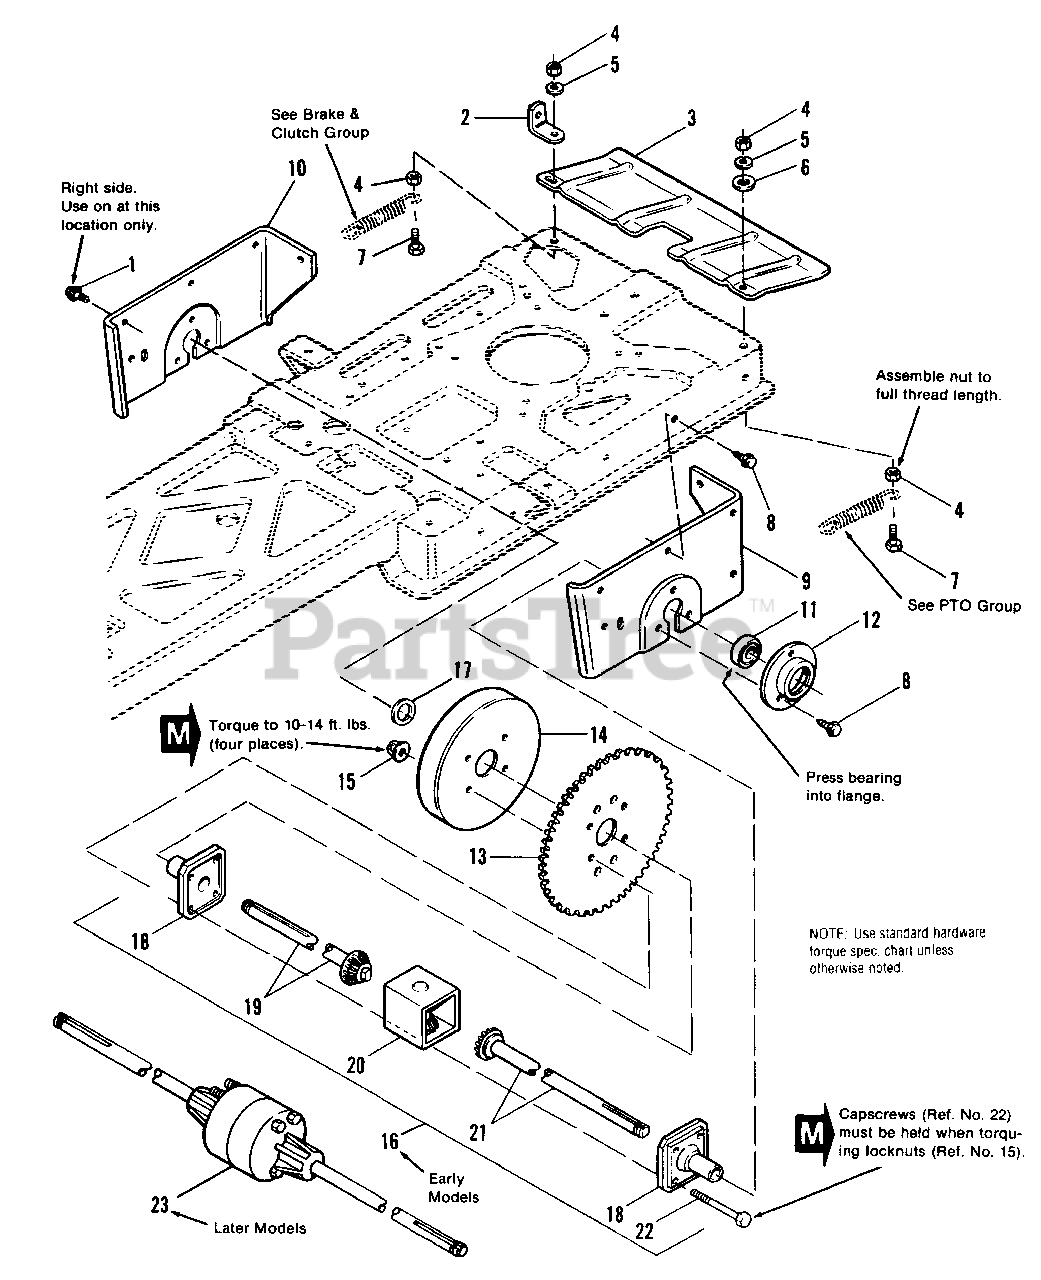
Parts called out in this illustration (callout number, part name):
1	SCREW, Hex, Wash. Hd., Taptite, 5/16-18 x 3/8
3	DEFLECTOR, Heat
4	NUT, Hex, 5/16-18
5	LOCKWASHER, 5/16
6	WASHER, Plain, 5/16
7	CAPSCREW, Hex, 5/16-18 x 1-1/2
8	SCREW, Taptite, Washer Hd., 5/16-18 x 1/2
9	AXLE SUPPORT, L.H.
10	AXLE SUPPORT, R.H.
11	BEARING, Ball
12	FLANGE, Bearing
14	DRUM, Brake
15	LOCKNUT, Hex, Flange, 5/16-18
16	**DIFFERENTIAL SERVICE KIT (Includes Ref. Nos. 13, 14, 15, 17 & 23)
17	WASHER, Plain
18	*END CAP & BEARING ASSY.*
19	*AXLE GEAR ASSY., R.H.*
20	*TRANSMISSION GEAR CASE ASSY.*
21	*AXLE GEAR ASSY., L.H.*
22	*CAPSCREW, Hex, 5/16-18 x 3-1/2*
23	***DIFFERENTIAL AXLE ASSY., Peerless, Model 100-009 (See note below.)
